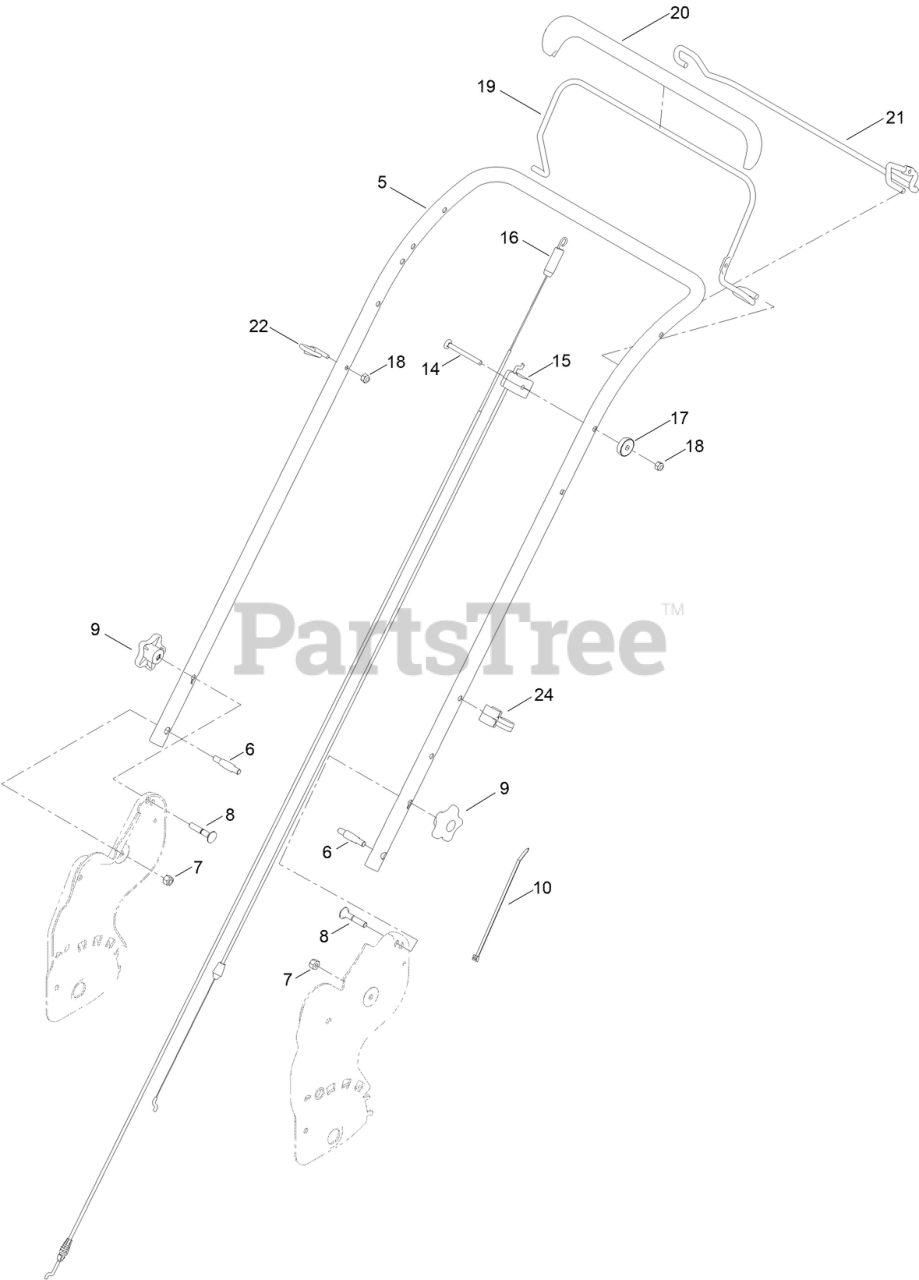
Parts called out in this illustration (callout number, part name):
5	HANDLE-CURVED
6	BOLT-SHOULDER, HANDLE
7	NUT-LOCK, NI
8	SCREW-CARR
9	KNOB-HANDLE
10	TIE-CABLE
14	SCREW-CARR
15	CABLE-BRAKE, FWD
16	CABLE-TRACTION, FWD
17	WASHER-CURVED
18	NUT-LOCK, NI
19	BAIL-BRAKE
20	COVER-BAIL
21	BAIL-TRACTION
22	GUIDE-ROPE
24	GUIDE-CABLE
